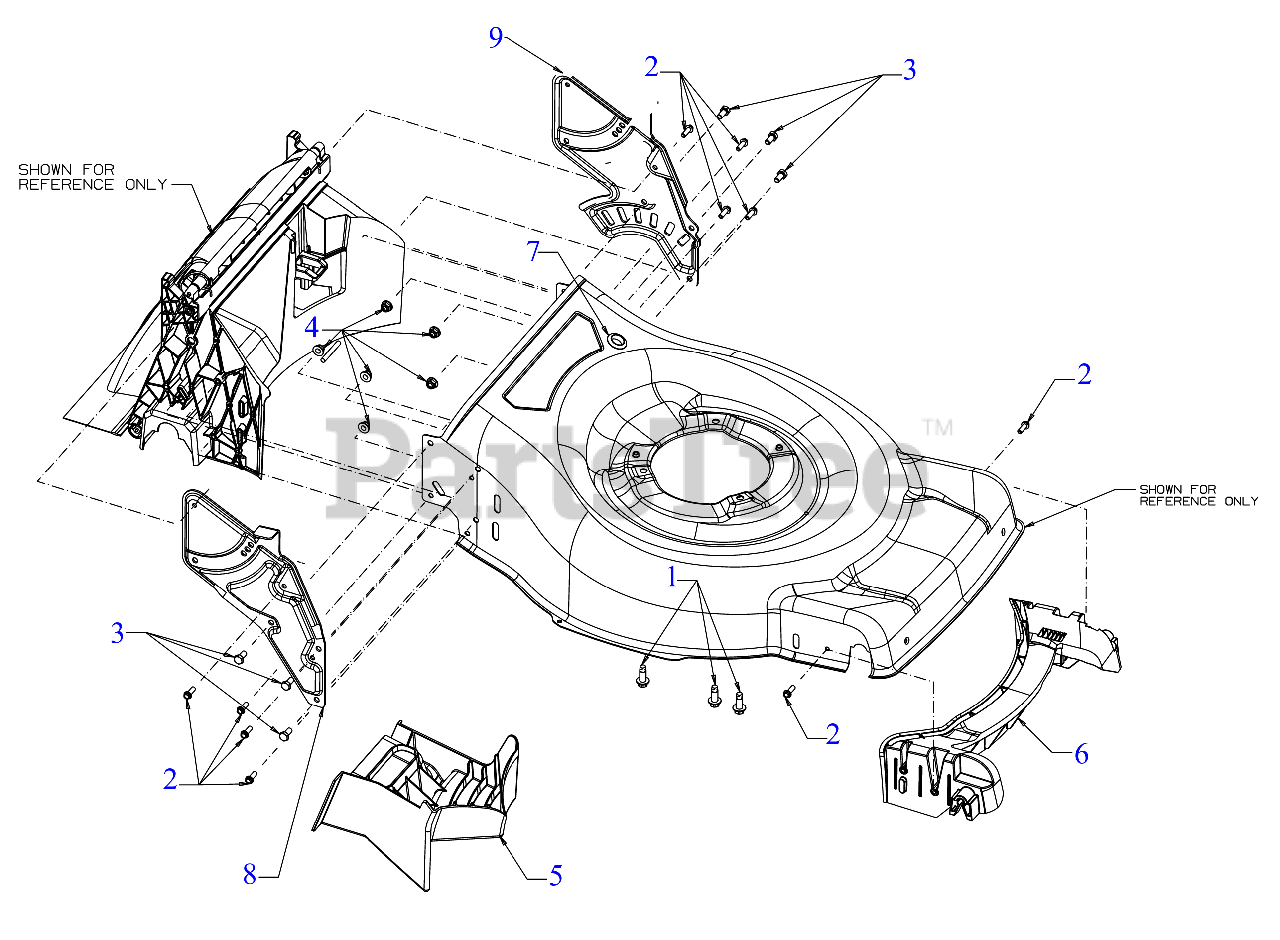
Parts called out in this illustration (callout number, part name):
1	SCREW 3/8-16 x 1
2	SCREW 1/4 x .750
3	SCREW 5/16-18X .625 GR5
4	FLANGE LOCK NUT 5/16-18
5	23" MULCH PLUG
6	23" BAFFLE (FRONT)
7	RUBBER GROMMET
8	23" HANDLE BRACKET (RH)
9	23" HANDLE BRACKET (LH)
